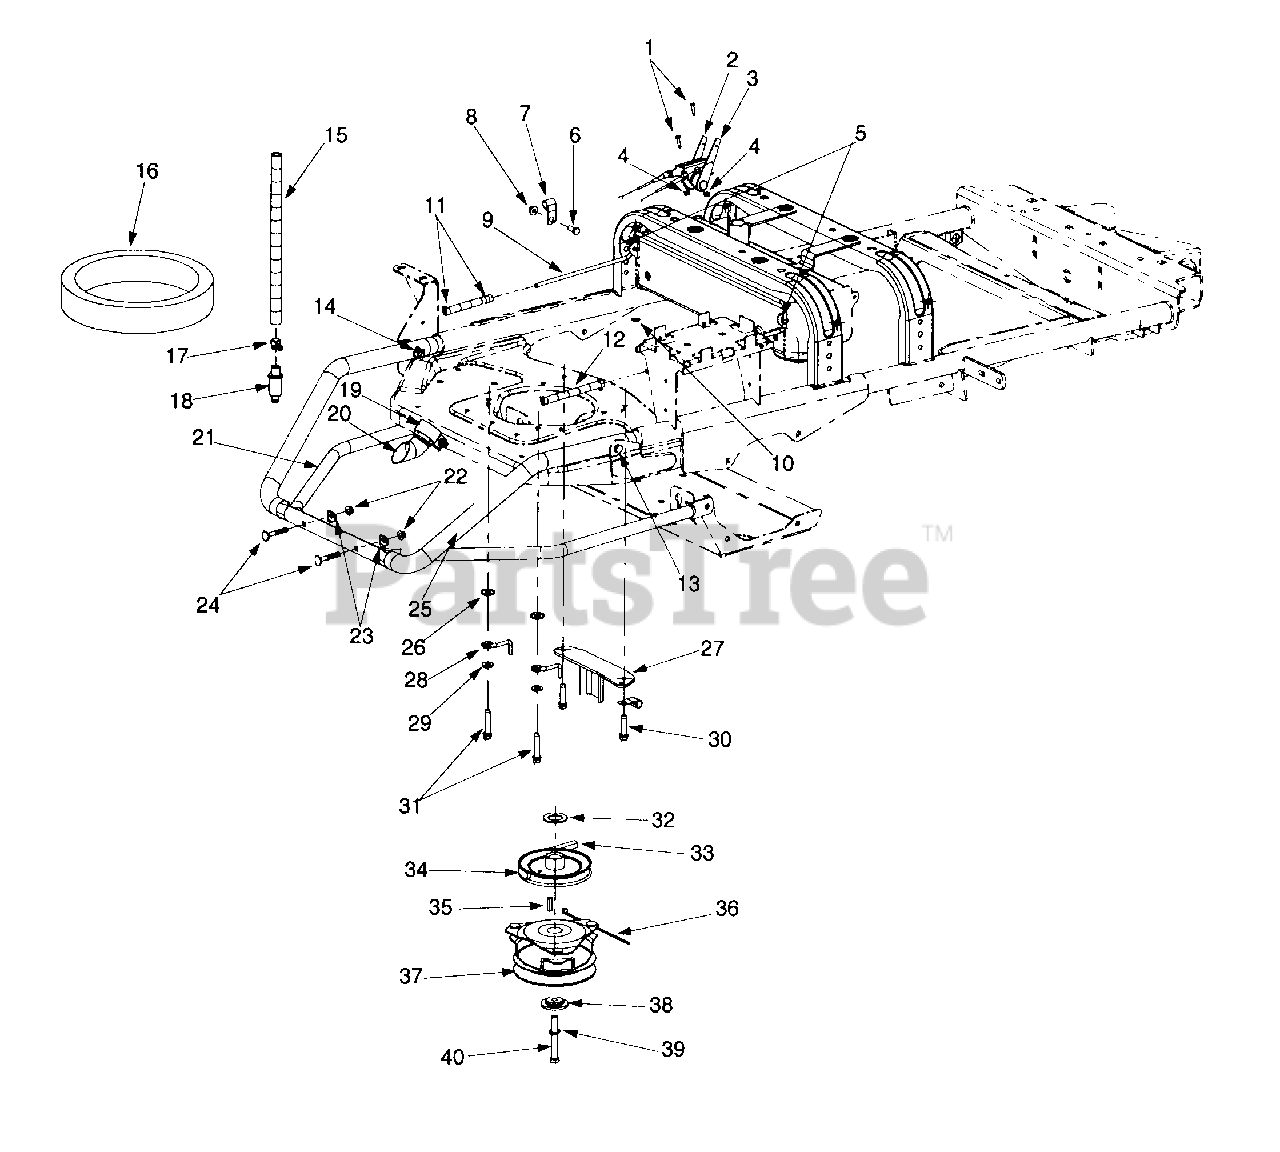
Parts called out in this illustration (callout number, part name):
1	Screw #10-24 x .750
2	Throttle Control Cable 40.5"
3	Choke Control Cable 38.0"
4	Lock Nut #10-24
5	Retainer Clip
6	Hex Cap Screw 5/16-18 x .75
7	Cable Clip Heat Shield
8	Hex Lock Nut 5/16-18
9	Fuel Line
10	Lock Washer 5/16
11	Hose Clamp
12	Fuel Line Hose
13	Hex Cap Screw 3/8-16 x 2.0
14	Flange Lock Nut 3/8-16
15	Oil Drain Hose
16	Gasket Foam Seal Ring
17	Oil Drain Cap
18	Oil Drain
19	Muffler Exhaust Clamp
23	Shoulder Washer .320 ID x .93 OD
24	Carriage Bolt 5/16-18 x 2.0
29	Flat Washer .407 I D x .812 OD
30	Hex Washer Screw 3/8-16 x 1.5
31	Hex Washer Screw 3/8-16 x 1.875
32	Flat Washer 1.0 ID x 1.75 OD
33	V-Belt
34	Drive Pulley
36	Cable Tie
37	Electric PTO Clutch
38	Spacer Clutch
39	Lock Washer 7/16
40	Hex Cap Screw 7/16-20 x 3.25
